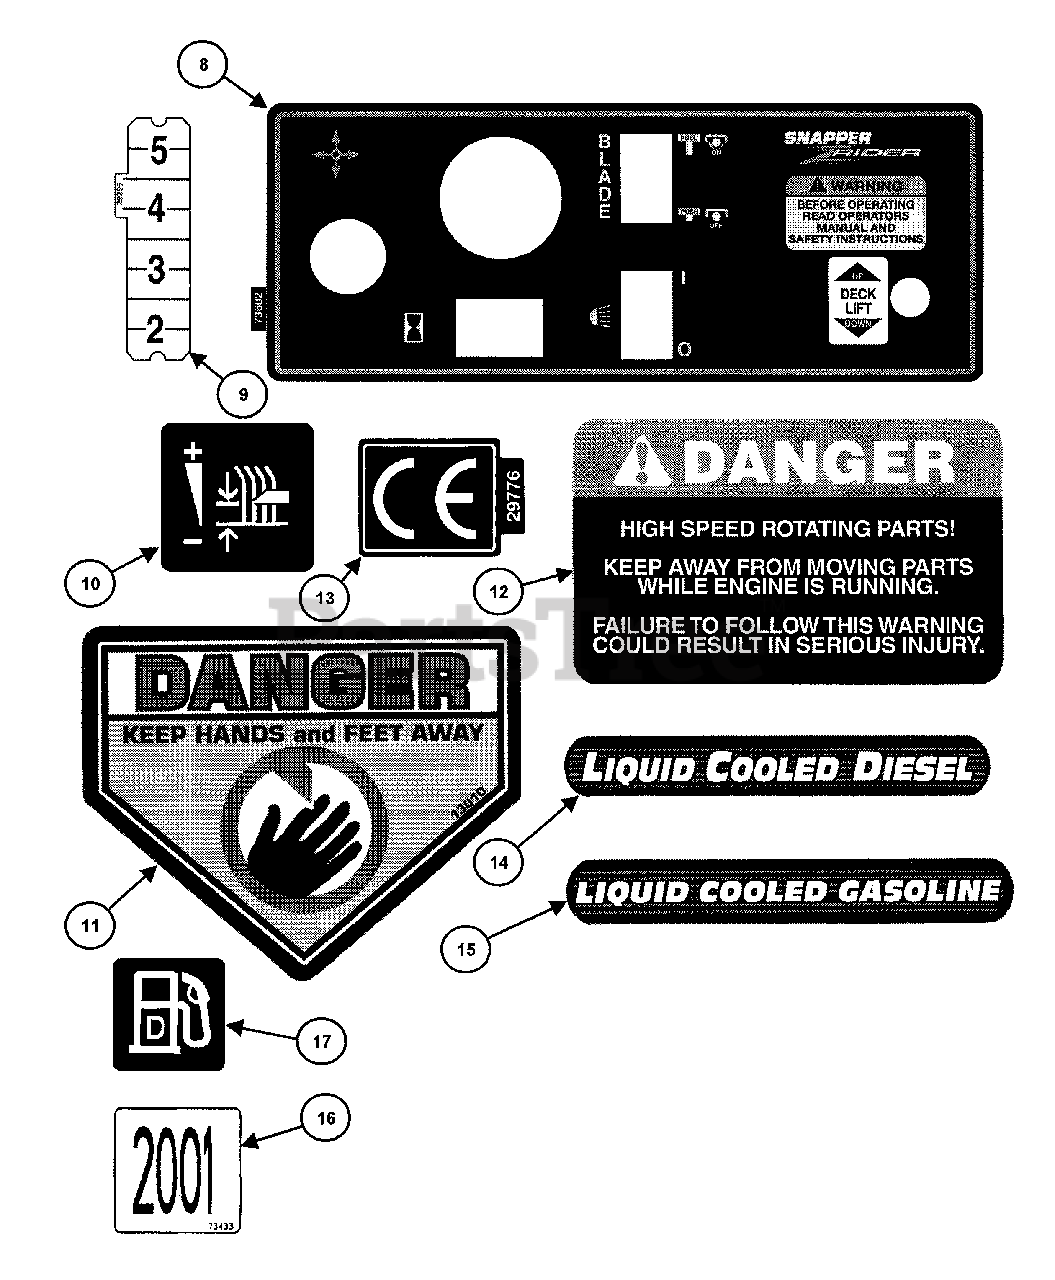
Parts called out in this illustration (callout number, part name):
8	DECAL, Instrument Panel OFD
9	DECAL, Height-of-Cut
10	DECAL, Height-of-Cut (Euro)
11	DECAL, Warning (CPSC Cut-Finger)
12	DECAL, Danger (Rotating Parts)
13	DECAL, European Community (EC)
14	DECAL, Liquid Cooled Diesel
15	DECAL, Liquid Cooled
16	DECAL, 2001 Year of Manufacture
17	DECAL, Diesel Fuel
